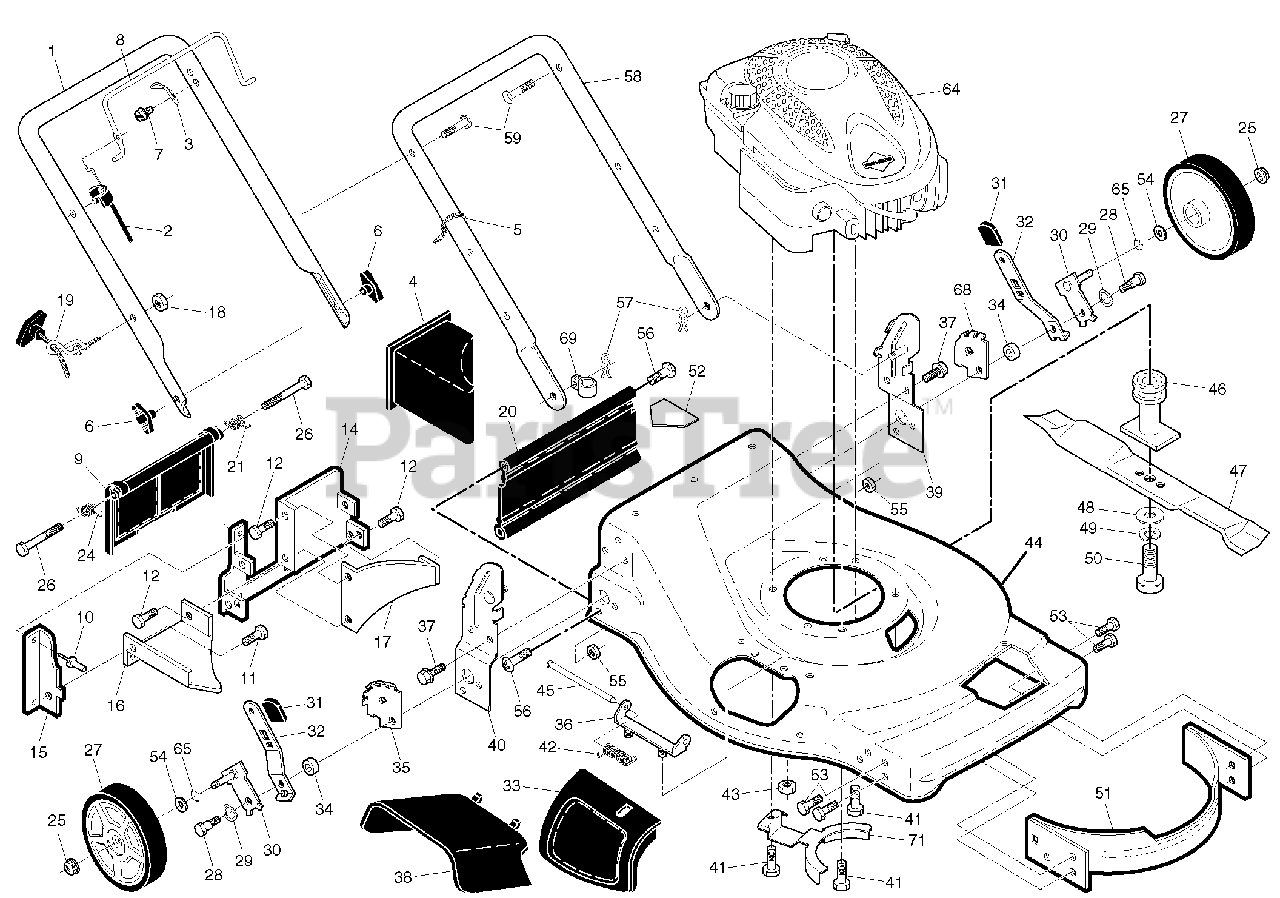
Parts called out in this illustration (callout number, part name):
1	Upper Handle
2	Cable, Operator Presence
3	Bracket, Upstop
4	Mulcher Plug
5	Wire Tie
6	Handle Knob
7	Screw
8	Control Bar
9	Rear Door Assembly
10	Pop Rivet
11	Screw, Self-Tapping #10-24 x 5/8
12	Screw, Hex Hex Head, Sems 1/4-20 x 1/2
14	Back Plate
15	Side Baffle
16	Discharge Baffle
17	Rear Baffle
18	Keps Locknut 1/4-20
19	Rope Guide
20	Rear Skirt
21	Spring, Rear Door, LH
24	Spring, Rear Door, RH
25	Nut, Hex, Flanged
26	Bolt, Rear Door
27	Wheel & Tire Assembly, Rear
28	Bolt, Shoulder 3/8-16 x 1
29	Washer, Curved, Cylindrical
30	Axle Arm Assembly
31	Selector Knob
32	Selector Spring
33	Mulcher Door
34	Spacer
35	Wheel Adjusting Bracket, RH
36	Hinge Bracket Assembly
37	Screw, Sems, Thread Cutting 5/16-18 x 3/4
38	Discharge Deflector
39	Handle Bracket Assembly, LH
40	Handle Bracket Assembly, RH
41	Screw, Hex Head, Threaded, Rolled 3/8-16 x 1-1/8
42	Spring, Torsion
43	Nut, Hex, Nylock
44	Kit, Mower Housing
45	Rod, Hinge
46	Blade Adapter / Pulley
47	Blade, 22"
48	Washer, Hardened
49	Washer, Helical
50	Screw, Machine, Hex Head 3/8-24 x 1-3/8 Grade 8
51	Kit, Front Baffle
52	Danger Decal
53	Screw, Serrated, TT 1/4-20
54	Washer, Flat
55	Nut, Hex 3/8-16
56	Hinge Screw 1/4-20 x 1-1/4
57	Hairpin Cotter
58	Lower Handle
59	Handle Bolt
65	O-Ring
68	Wheel Adjusting Bracket, LH
69	Clip, Cable
71	Belt Keeper
